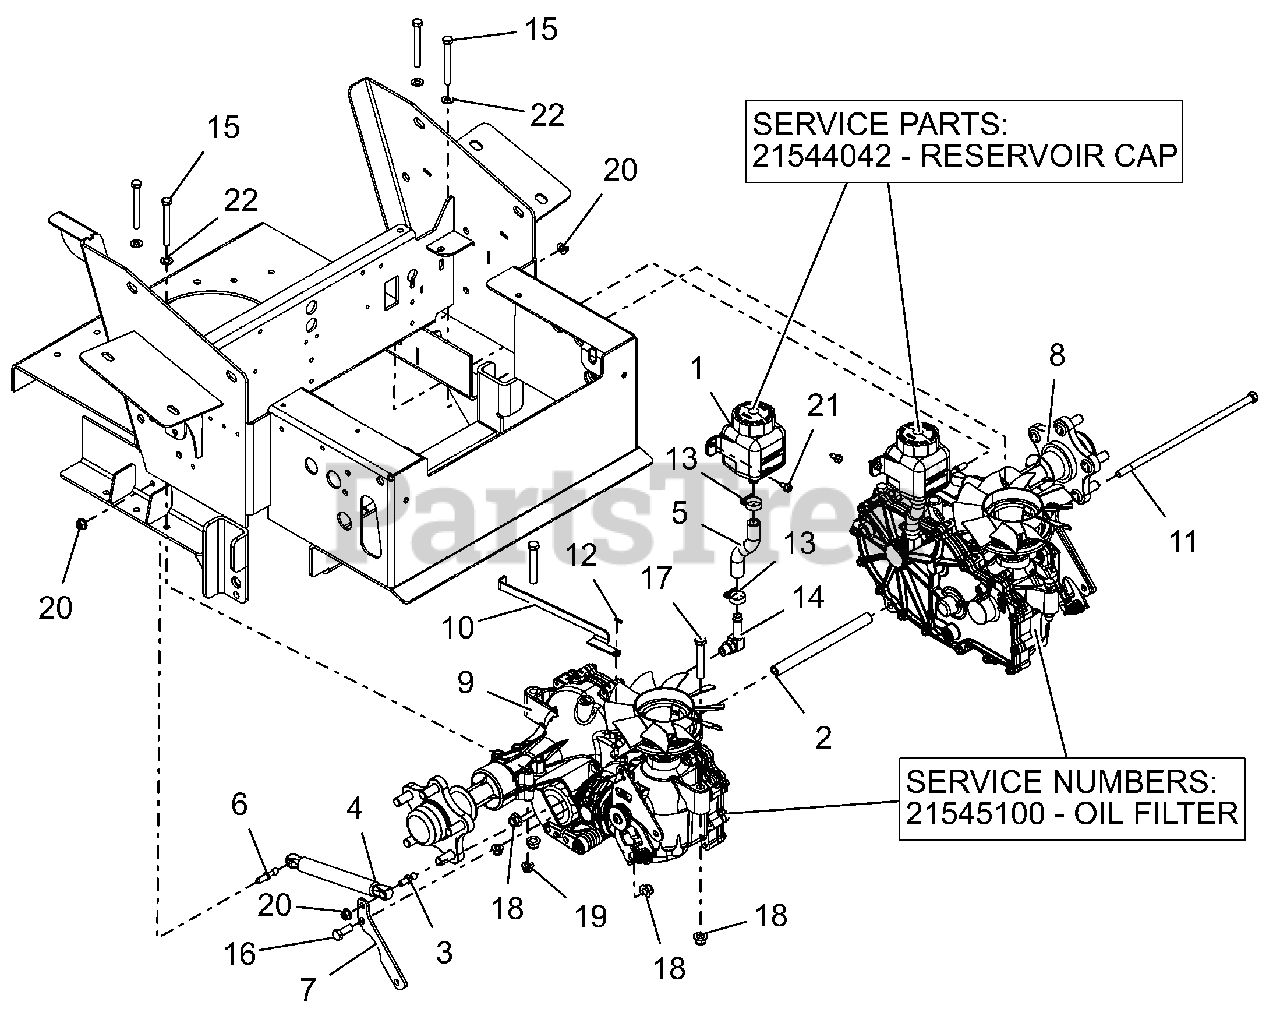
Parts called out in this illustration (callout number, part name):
1	TANK, EXPANSION
1	CAP, HYDRO RESERVOIR REPLAC.
2	SPCR,.406 ID X .630 OD X 7.724
3	STUD- BALL
4	DAMPER
5	HOSE, 100I HYDRO OVERFLOW
6	STUD-BALL-THREADED
7	TRANSMISSION DAMPER MTG PLT-BL
8	TRANSAXLE, ZT3200, LH
9	TRANSAXLE, ZT3200, RH
9	OIL FILTER, TRANSMISSION
10	DUMP VALVE BRKT - BLACK
11	BLT HEX, .38-16X11.00 GR5 YWZC
12	PIN-HAIR INT .06X.18X.77
13	CLAMP,.88 DIA. HOSE
14	FITTING, HYD (90 DEG)
15	@BLT-HEX .31-18X3.00 GR5 YWZC
16	@BLT-HEX .38-16X1.00 GR5 YWZC
17	@BLT-HEX .38-16X2.50 GR5 YWZC
18	@NUT-LK-NYL-FLG .38-16 YWZC
19	@NUT-LK-NYL-FLG .31-18 YWZC
20	@NUT-LK-TOP-FLG .31-18 YWZC
21	SCR-TAP .25-20X.50 HWH TR YWZ
22	@WSHR-FL-STL.344X.688X.065YWZC
